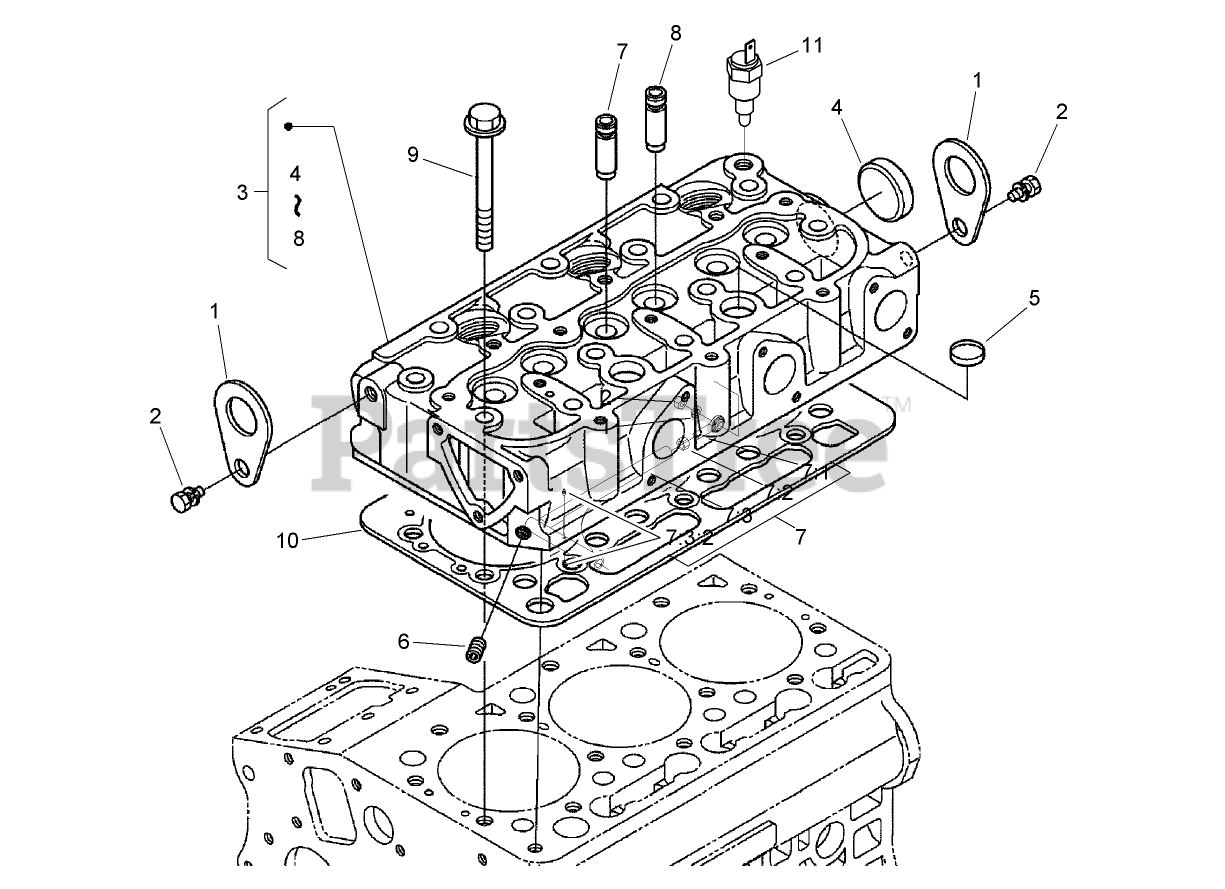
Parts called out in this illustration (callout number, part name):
1	HOOK-ENGINE
3	HEAD-CYLINDER
4	CAP-SEALING
5	CAP-SEALING
6	PLUG
7	GUIDE-VALVE, INLET
8	GUIDE-VALVE, EXHAUST
9	BOLT-HEAD, CYLINDER
10	GASKET-HEAD, CYLINDER
11	THERMOSWITCH
